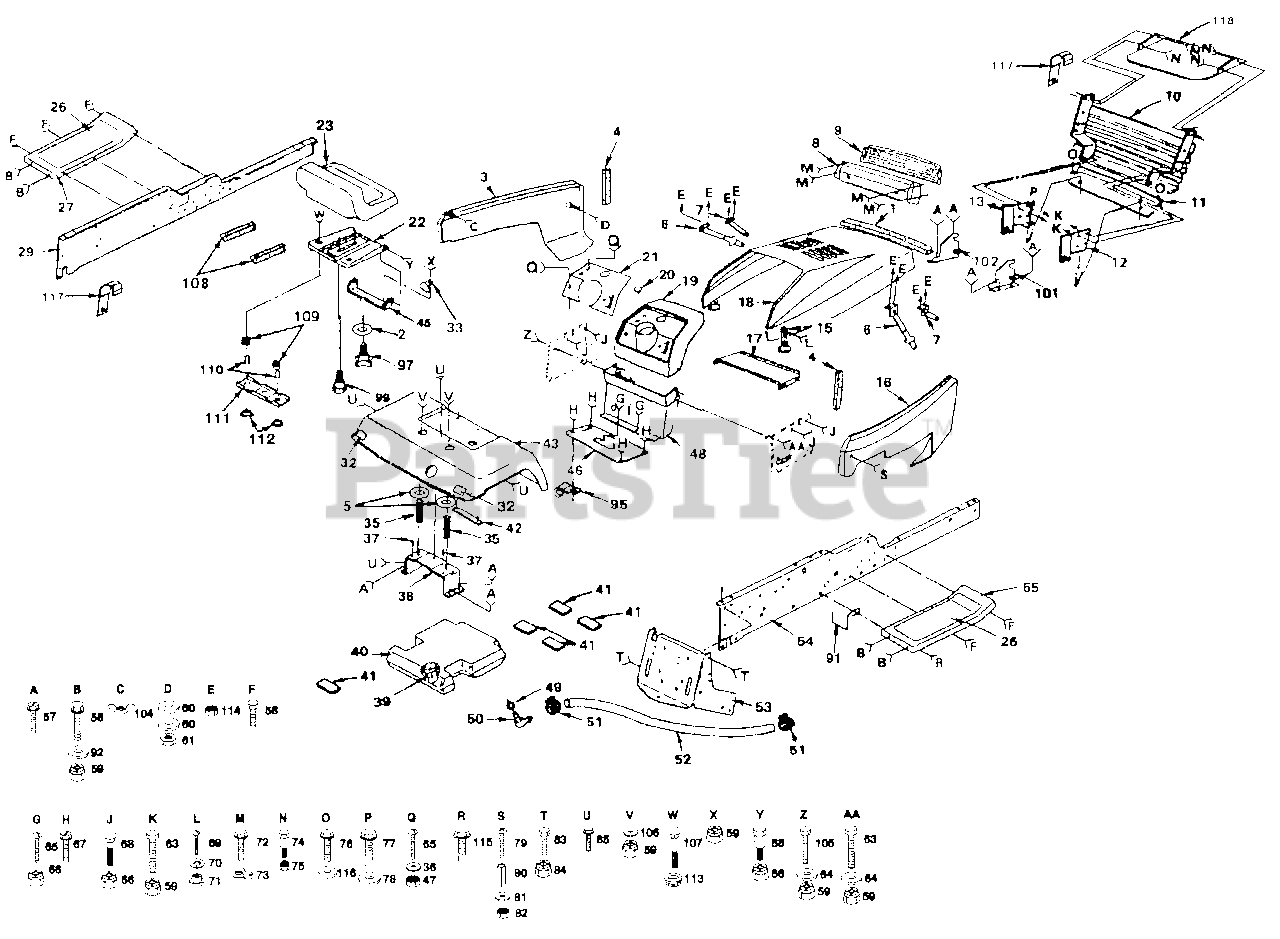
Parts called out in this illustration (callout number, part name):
1	Strip, Foam (AYP part number)
2	Washer 17/32 x 1-3/16 x 12 Ga. (AYP part number)
3	Panel-Side, L.H. (AYP part number)
4	Strip, Foam (AYP part number)
5	Cap, Spring (AYP part number)
6	Strap Assembly-Hinge, Rear (AYP part number)
7	Strap Assembly-Hinge, Front (AYP part number)
8	Bezel Assembly
9	Lens (AYP part number)
10	Grill Assembly (AYP part number)
11	Strap, Grill (AYP part number)
12	Support, Grill, R.H. (AYP part number)
13	Support, Grill, L.H. (AYP part number)
15	Latch, Hood (AYP part number)
16	Panel, Side, R.H. (AYP part number)
17	Support, Battery (AYP part number)
18	Hood (AYP part number)
19	Dashboard (AYP part number)
20	Plug, Dash (AYP part number)
21	Dashplate (AYP part number)
22	Pan, Seat (AYP part number)
23	Seat (AYP part number)
26	Pad, Footrest (AYP part number)
27	Footrest, L.H. (AYP part number)
29	Rail, Frame, L.H. (AYP part number)
32	Reflector, Taillight (AYP part number)
33	Clip, Insulated (AYP part number)
35	Spring, Compression (AYP part number)
36	Washer 11/32 x 11/16 x 16 Ga. (AYP part number)
37	Nut, Push (AYP part number)
38	Bracket, Fender (AYP part number)
39	Cap, Fuel (AYP part number)
40	Tank, Fuel (AYP part number)
41	Pad, Spacer (AYP part number)
42	Strap, Fender (AYP part number)
43	Fender (AYP part number)
45	Bracket, Pivot, Seat (AYP part number)
46	Cover, Shift-Gate (AYP part number)
47	Nut, Keps 5/16-18 (AYP part number)
48	Dash Assembly (AYP part number)
49	Bushing (AYP part number)
50	Stem, Tank Fuel (AYP part number)
51	Clamp, Hose (AYP part number)
52	Line, Fuel (AYP part number)
53	Drawbar (AYP part number)
54	Rail, Frame, R.H. (AYP part number)
55	Footrest, R.H. (AYP part number)
57	Screw, Hex Washer Thread Rolling 3/8-16 x 3/4 (AYP part number)
58	Bolt, Hex 3/8-16 x 3/4 (AYP part number)
59	Nut, Crownlock 3/8-16
60	Washer 9/32 x 3/4 x 16 Ga. (AYP part number)
61	Nut, Hex 1/4-20 (AYP part number)
63	Bolt, Hex 3/8-16 x 1 (AYP part number)
64	Washer 13/32 x 13/16 x 16 Gauge (AYP part number)
65	Screw, Mach. Cr., Thd. 5/16-18 x 3/4 (AYP part number)
66	Nut, Crownlock 5/16-18
67	Screw, Hex Washer Thd. Cutting 1/4-20 x 1/2 (AYP part number)
68	Bolt, Carriage 5/16-18 x 3/4
69	Screw, Cr., Pan. Mach. #10-24 x 1/2 (AYP part number)
70	Washer, Lock #10 (AYP part number)
71	Nut, Weld (AYP part number)
72	Screw, Hex Washer Hd Tap #10-16 x 5/8 (AYP part number)
73	"J" Fastener (AYP part number)
74	Bolt, Shoulder 1/4-20 (AYP part number)
75	Nut, Crownlock 1/4-20 (AYP part number)
76	Screw, Hex Washer Thd. Roll 1/4-20 x 3/4 (AYP part number)
77	Screw, Hex Washer Hd. Thd. Roll 5/16-18 x 3/4
78	Washer 11/32 x 3/4 x 12 Ga. (AYP part number)
79	Screw, Mach. Cr. Pan #10-24 x 1-1/4 (AYP part number)
80	Spacer, Split #10 x 3/4 (AYP part number)
81	Washer 7/32 x 1/2 x 18 Ga. (AYP part number)
82	Nut, Keps #10-24 (AYP part number)
83	Bolt, Hex 7/16-14 x 1 (AYP part number)
84	Nut, Crownlock 7/16-14 (AYP part number)
85	Screw, Hex Washer Thread Rolling 3/8 x 16 x 1/2 (AYP part number)
88	Bolt, Shoulder (AYP part number)
91	Retainer, Belt, Lower (AYP part number)
92	Washer 13/32 x 13/16 x 17 Gauge (AYP part number)
95	Clip, Insulated
97	Knob (AYP part number)
99	Bolt, Shoulder 5/16-18 x .62 (AYP part number)
101	Bracket, Assembly Pivot Frame, R.H. (AYP part number)
102	Bracket, Assembly Pivot Frame, L.H. (AYP part number)
104	Nut, Wing 1/4-20 (AYP part number)
105	Bolt, Hex 3/8-16 x I-1/4 (AYP part number)
106	Washer 13/32 x 1 x 14 Gauge (AYP part number)
107	Bolt, Carriage 1/4-20 x 1-3/8
108	Foam, Strip (AYP part number)
109	Spring, Compression (AYP part number)
110	Spacer, Split (AYP part number)
111	Bracket, Switch (AYP part number)
112	Bushing, Snap (AYP part number)
113	Locknut, Flange 1/4-20 (AYP part number)
114	Nut, Hex 1/4-20 (AYP part number)
115	Screw, Thrdrol. 3/8-16 x 1 (AYP part number)
116	Washer 9/32 x 5/8 x 16 (AYP part number)
117	Clip, Insulated (AYP part number)
118	Shield, Heat, Front (AYP part number)
